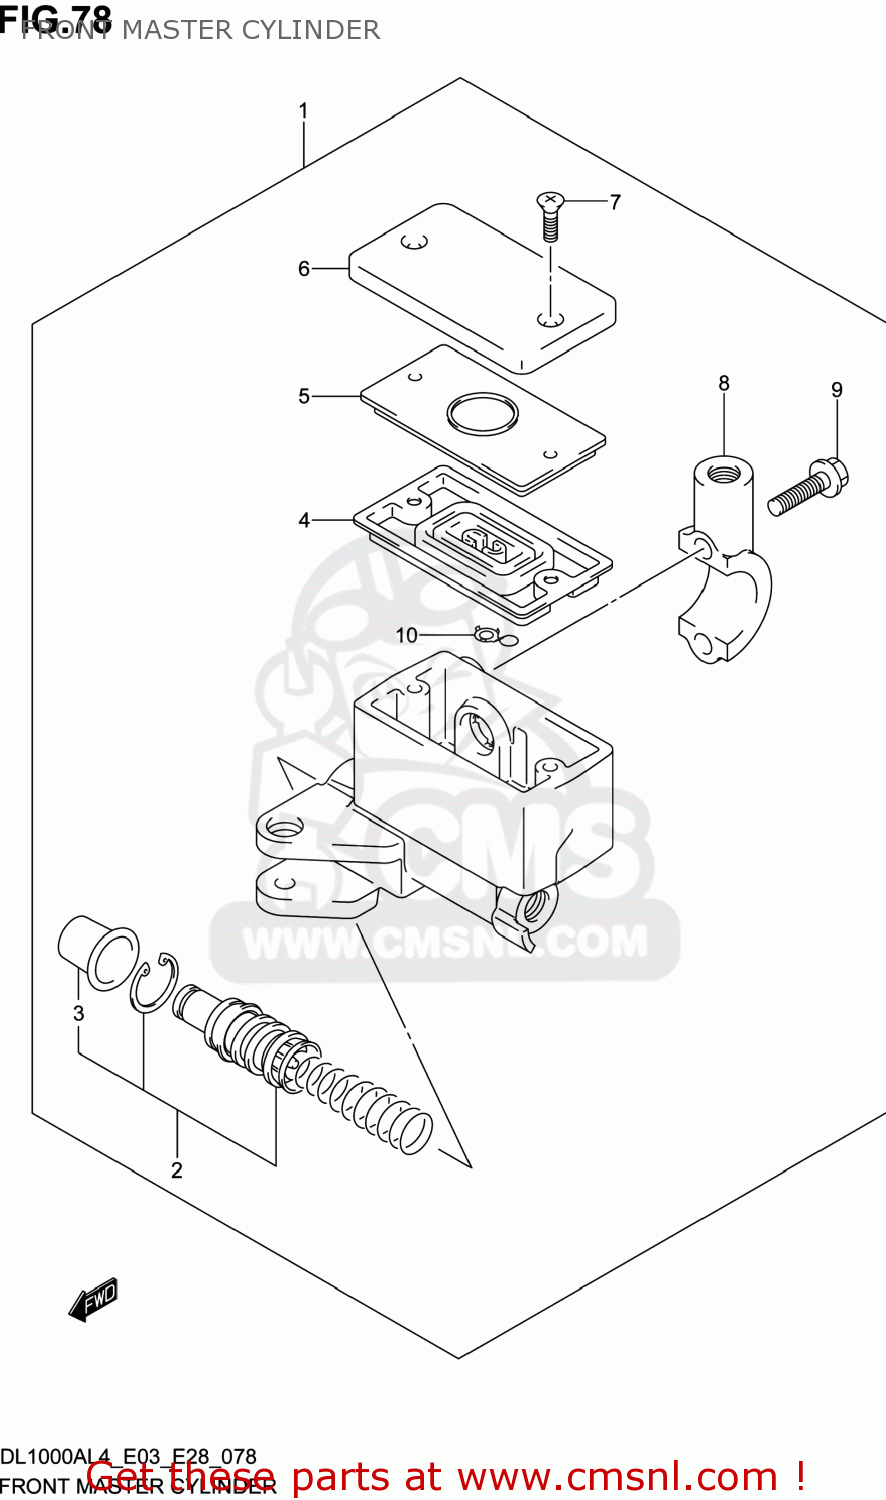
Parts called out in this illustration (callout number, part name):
1	CYLINDER ASSY,FR MASTER
2	PISTON & CUP SET
3	BOOT
4	5
5	PLATE,DIAPHRAGM
6	CAP
7	SCREW
8	HOLDER
9	BOLT(6X22)
10	PROTECTOR
